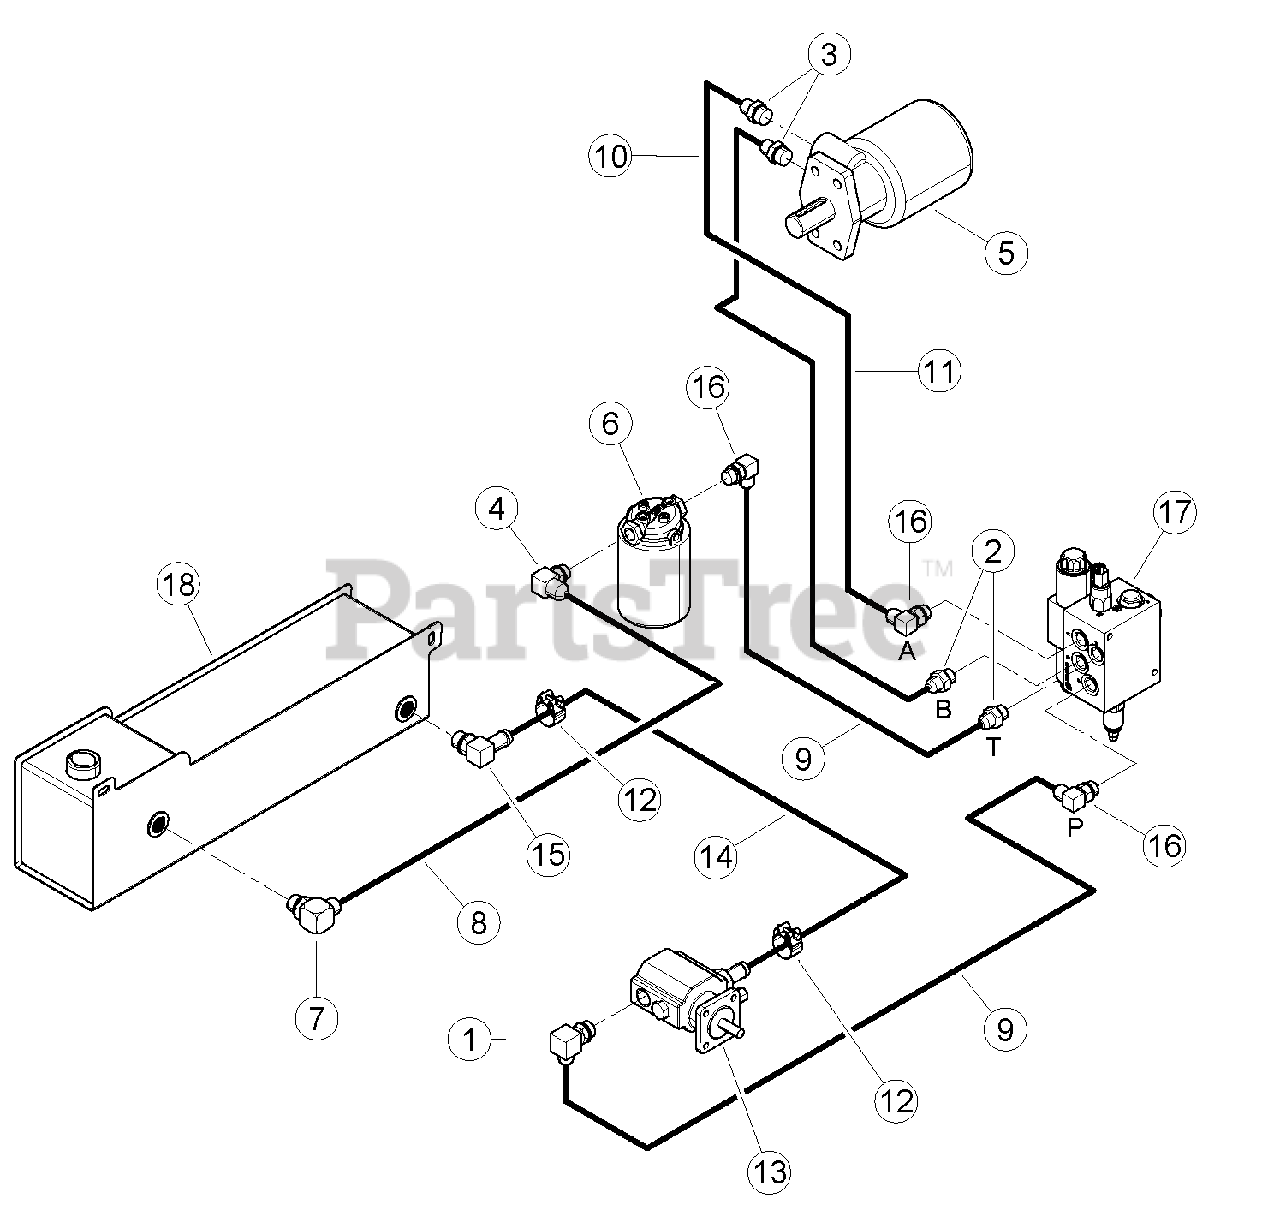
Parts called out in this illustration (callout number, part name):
1	ADAPTER, -10 MORING / -8 MJIC 90 DEG.
2	ADAPTER, -8 MORING / -8 MJIC
3	ADAPTER, -10 MORING / -8 MJIC
4	ADAPTER, -8 MORING / -10 MJIC 90 DEG.
5	MOTOR, 45 CU IN HYDRAULIC
6	ASSEMBLY, HYDRAUILC FILTER
7	ADAPTER, -10 MORING / -10 MJIC 90 DEG.
8	HOSE ASSEMBLY, -10 FMJ / -10 FMJ LD 90 DEG. X 21"
9	HOSE ASSEMBLY, -8 FMJIC / -8 FMJIC 90 DEG. X 21"
10	HOSE ASSEMBLY, -8 FMJIC / -8 FMJIC 90 DEG. X 61"
11	HOSE ASSEMBLY, -8 FMJIC / -8 FMJIC X 61"
12	CLAMP, 1-5/32 TO 7/32 OD RANGE T-BOLT
13	PUMP, 2 STAGE CW HI/LO 0.605 DISP.
14	HOSE, .75 ID X 24 IN. 100R4 HYD
15	ADAPTER, -10 MORING / .75 90 DEG. HOSE
16	ADAPTER, -8 MORING / -8 MJIC 90 DEG.
17	ASSEMBLY, HYDRAULIC FEED FLOW VALVE
18	WELDMENT, HYDRAULIC TANK
